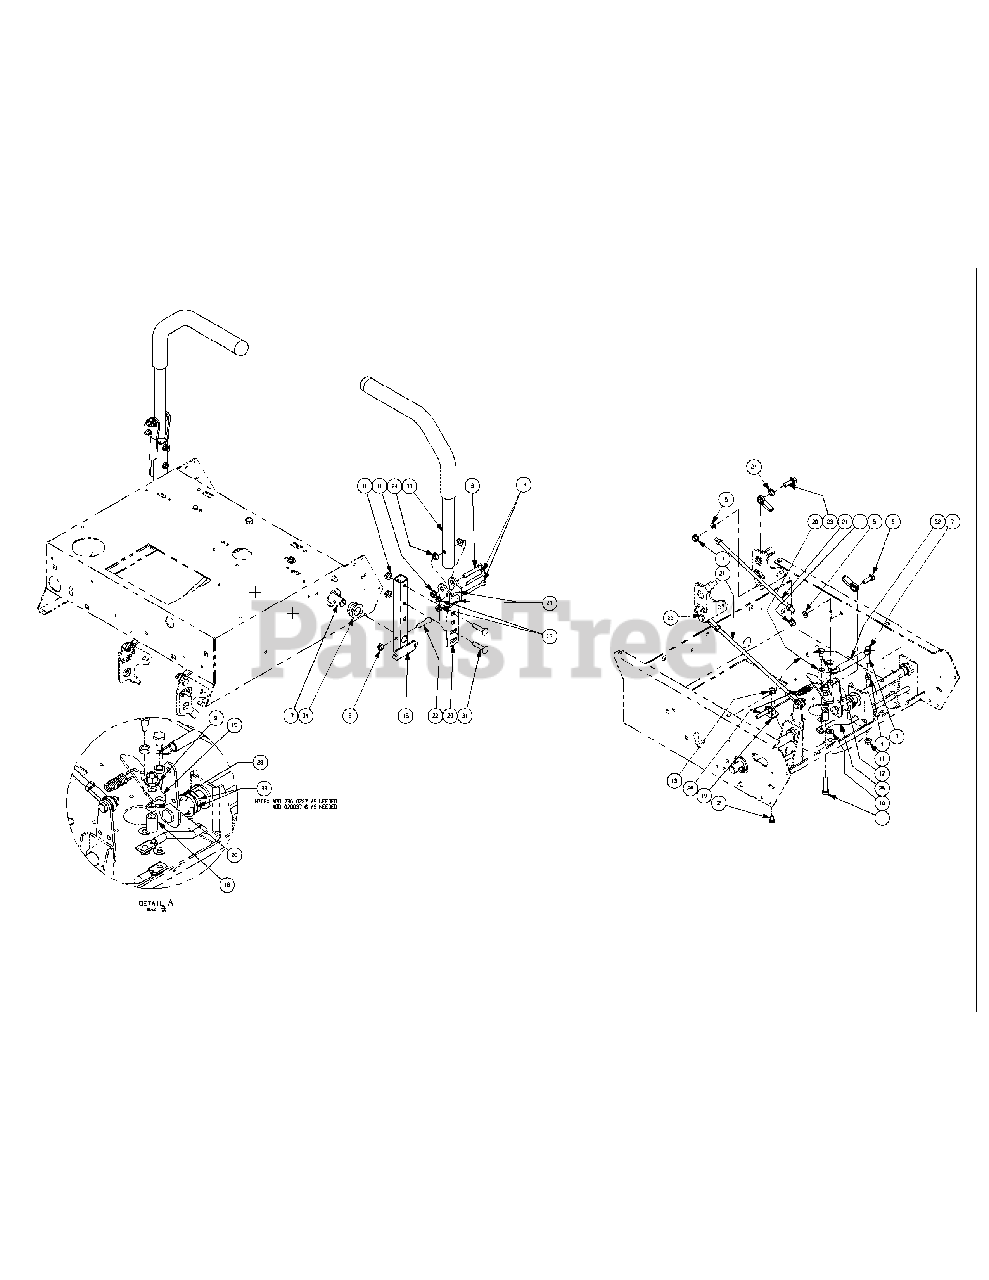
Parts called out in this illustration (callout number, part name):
1	Hex Cap Screw, 3/8-16 x 1-1/2
2	Hex Cap Screw, 1/4-20 x 1/2
3	Nylock Nut, 5/16-18
4	Hex Nut, 5/16-18
5	Flat Washer, 5/16
6	Hex Head Cap Screw, 5/16-18 x 1.00
7	Hex Cap Screw, 5/16-18 x 1-1/2
8	Hex Cap Screw, 5/16-18 x 2.00
9	Nut, Flange Lock, 3/8-16
10	Flat Washer, 1.4 x .630 x .0515
11	Nut, 5/16-18, Lock
12	Shoulder Screw, 1/4-28
13	Nut, 1/4-20, Hex Flange Lock Nut
14	Hex Cap Screw, 1/4-20 x 2.00
15	Brake Lever Plate
16	Pivot Bracket Weldment
17	Steering Input Shaft Assembly
18	Spacer, .385 ID x .625 OD x .869
19	Brake Cable Mounting Bracket
20	Spacer, .380 x .563 x .196
21	Steering Link Rod
22	Socket Head Capscrew, 5/16-18 x 1.25
23	HHCS, 5/16-18 x 1-1/4
24	Bushing, .310 x .172 x .688 x .06
25	Control Lock Rod
26	Control Cable Lock Out
27	Spacer, .25 ID x .38 OD x 1.13
28	Retainer Ring, E-Clip
29	Lapbar Pivot Bracket
30	Lapbar Assembly includes:
31	Carriage Bolt, 5/16-18 x 1.50
32	Extension Spring, .53 OD x 4.7
33	Flat Washer, .793 ID x 1.24 OD x .060
34	Hex Flange Bearing, .752 ID
